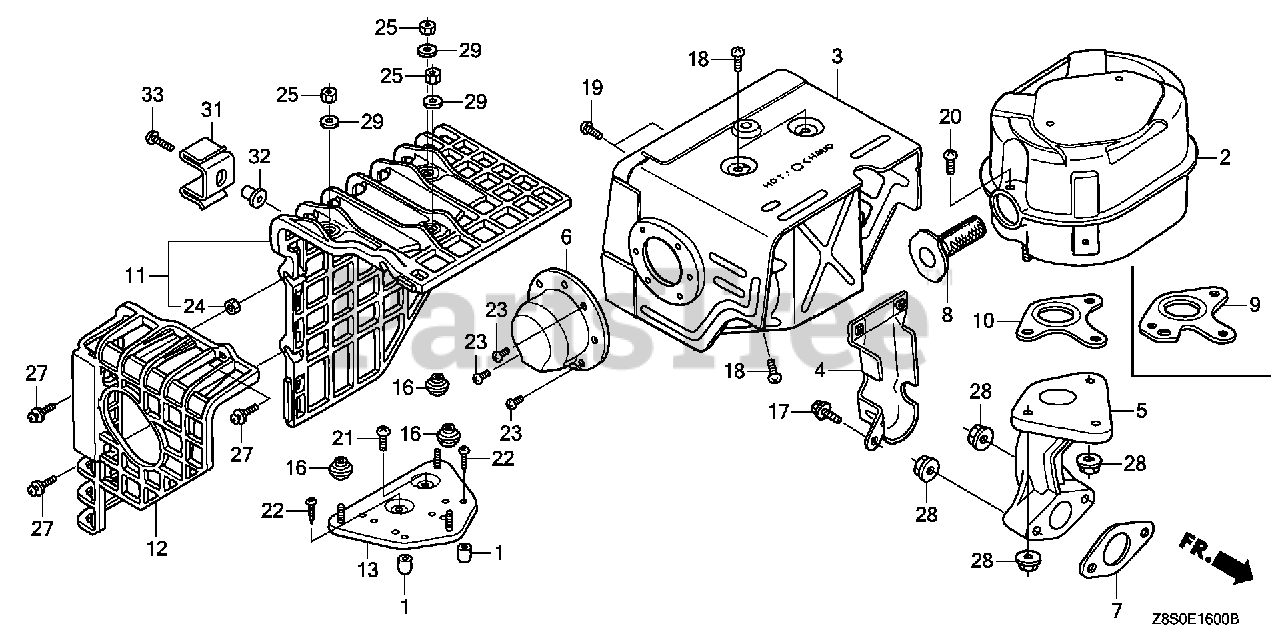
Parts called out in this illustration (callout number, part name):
2	MUFFLER
3	PROTECTOR, MUFFLER (STD)
4	PROTECTOR, EX. PIPE
6	CAP, MUFFLER
7	GASKET, EX. PIPE
8	ARRESTER, SPARK
9	GASKET, MUFFLER (ARRESTER) (NIPPON LEAKLESS)
10	GASKET, MUFFLER (NIPPON LEAKLESS)
10	GASKET, MUFFLER (THAI LEAKLESS)
17	BOLT, FLANGE (6X12) (CT200)
18	SCREW, TAPPING (5X8)
19	SCREW, TAPPING (5X8)
20	SCREW, TAPPING (4X6)
23	SCREW, TAPPING (4X6)
28	NUT, FLANGE (8MM)
